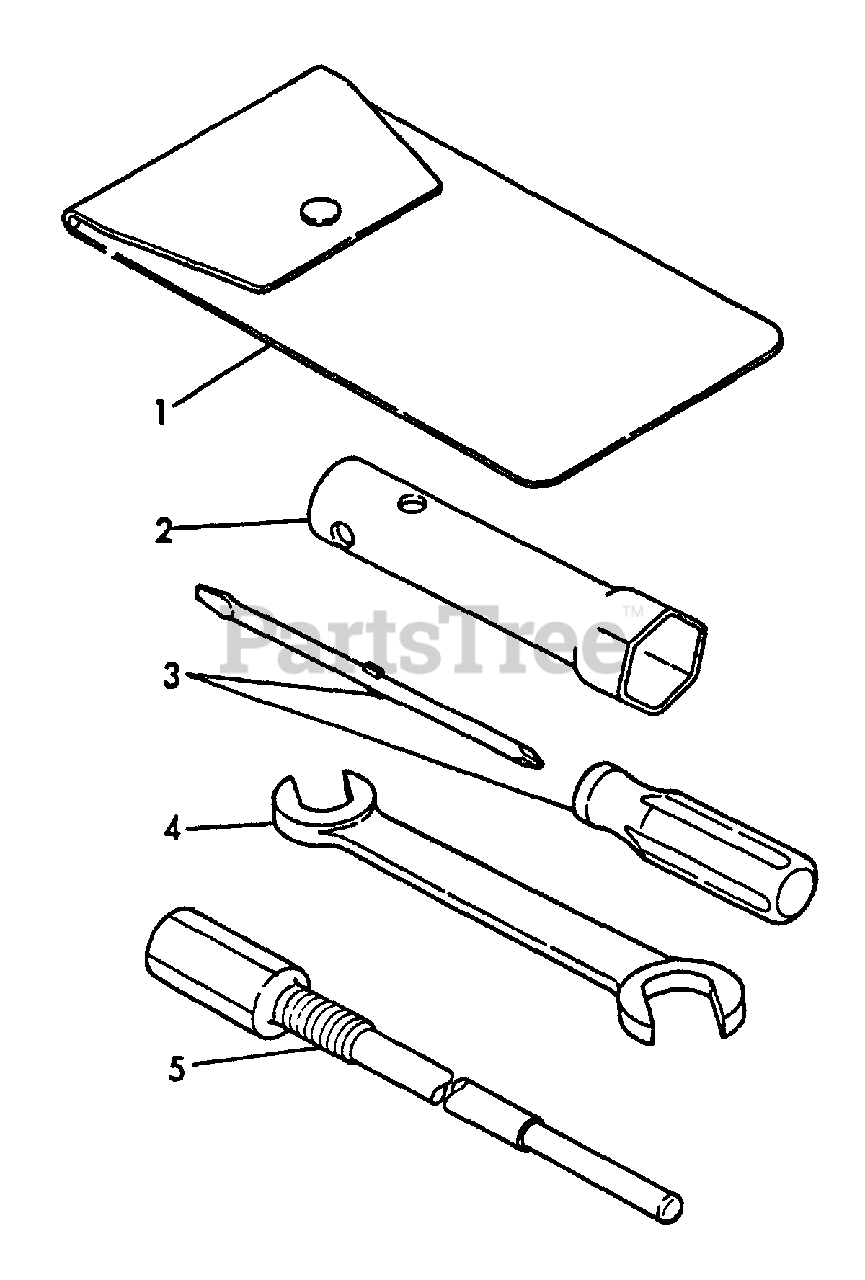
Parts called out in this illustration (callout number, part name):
1	BAG, TOOL
2	SOCKET WRENCH - 21mm
3	SCREWDRIVER
4	SPANNER - 10X12mm
5	TOOL, ROTOR REMOVAL
